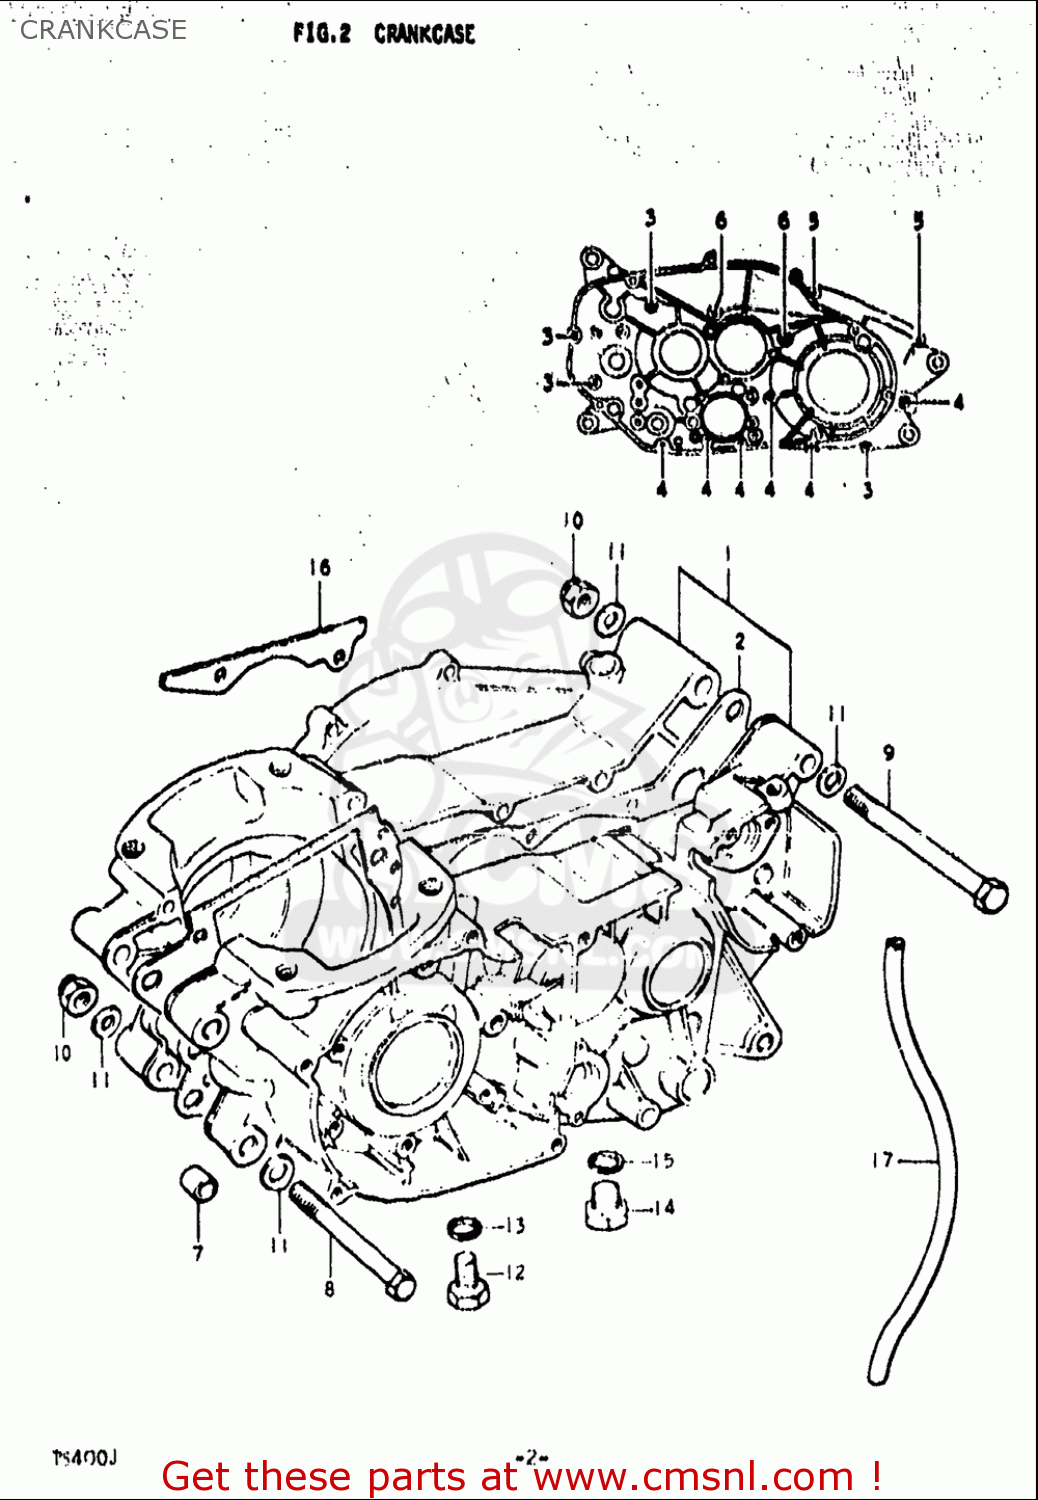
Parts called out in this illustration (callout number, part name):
2	GASKET,CRANKCASE (NAS)
3	SCREW
4	SCREW
5	SCREW
6	SCREW
7	PIN
8	BOLT
9	BOLT
10	NUT
11	WASHER
12	PLUG
13	GASKET(10X14X3.6) (NAS)
14	PLUG
15	GASKET(14X19.2X2) (NAS)
